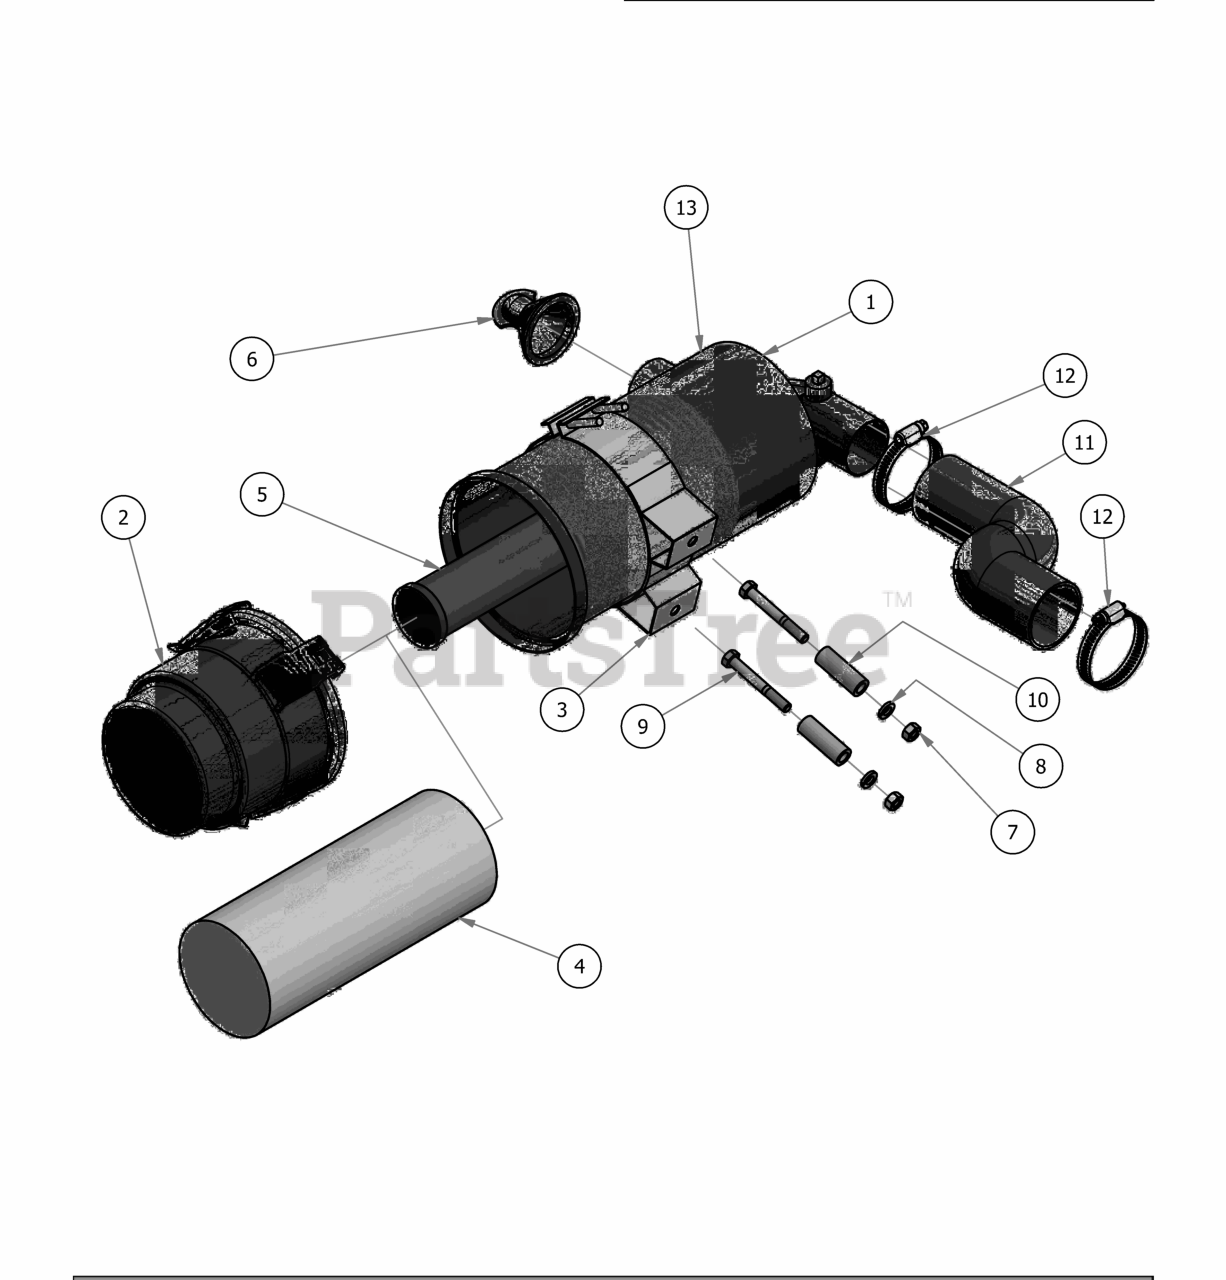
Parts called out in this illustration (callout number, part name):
1	Canister for All Diesel Models
2	Enginaire Air canister cap
3	Mounting Bracket For Diesel Air Filter
4	Diesel Air Filter- Outer
5	Diesel Air Filter- Inner
6	Debris Plug-Enginaire Filter
8	5/16" Lock Washer
9	5/16" x 2 1/2" Bolt
10	.378 x .625x 1.750 Spacer Zinc
11	Air Intake Hose-Diesel Air Filter Canister
12	2-1/2" Hose Clamp
13	Enginaire Canister VLR-Complete Assembly
